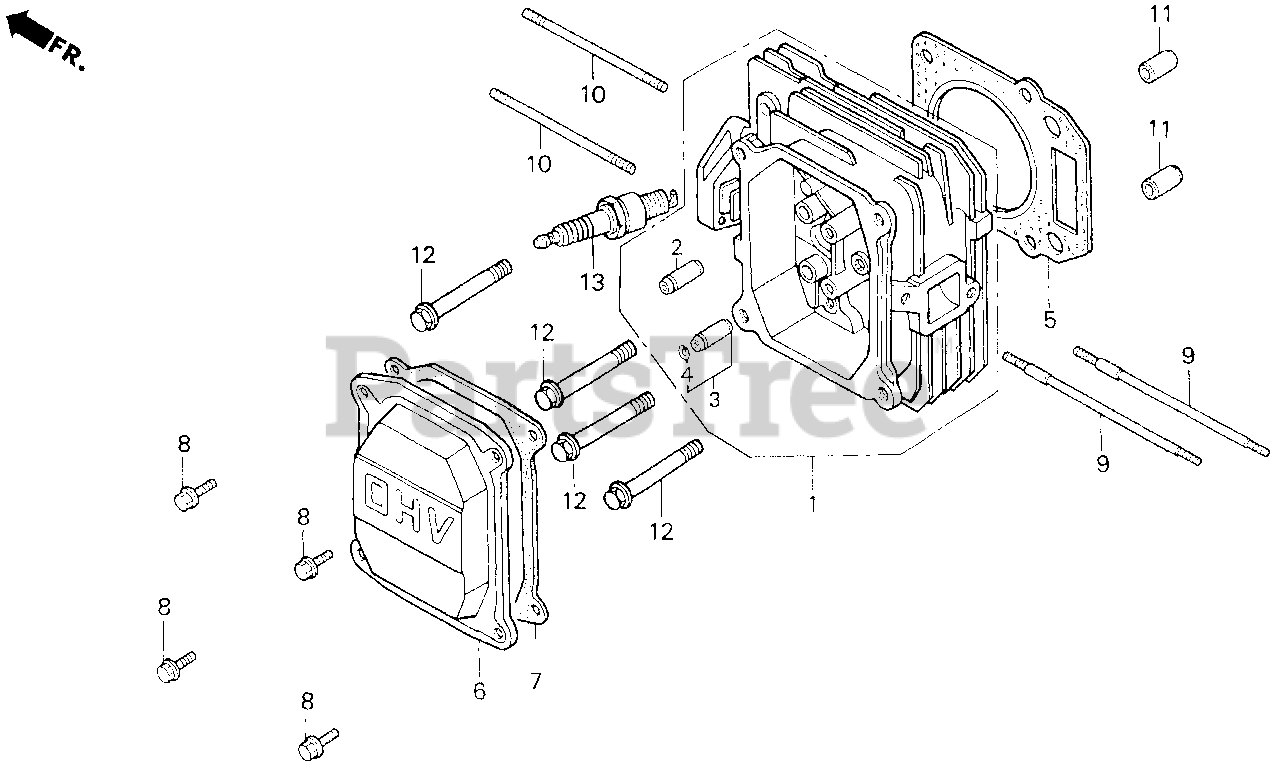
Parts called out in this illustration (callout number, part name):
1	CYLINDER HEAD
2	GUIDE, VALVE (OS)
3	GUIDE, EX. VALVE (OS)
4	CLIP, VALVE GUIDE
5	GASKET, CYLINDER HEAD
6	COVER, HEAD
7	GASKET, CYLINDER HEAD COVER
8	BOLT, FLANGE (6X12) (CT200)
9	BOLT, STUD (6X109)
10	BOLT, STUD (6X85)
11	PIN A, DOWEL (10X16)
12	BOLT, FLANGE (8X50)
13	SPARK PLUG (BPR4ES) (NGK)
13	SPARK PLUG (W14EPR-U) (DENSO)
13	SPARK PLUG (BPR5ES) (NGK)
13	SPARK PLUG (W16EPR-U) (DENSO)
13	SPARK PLUG (BPR6ES) (NGK)
13	SPARK PLUG (W20EPR-U) (DENSO)
